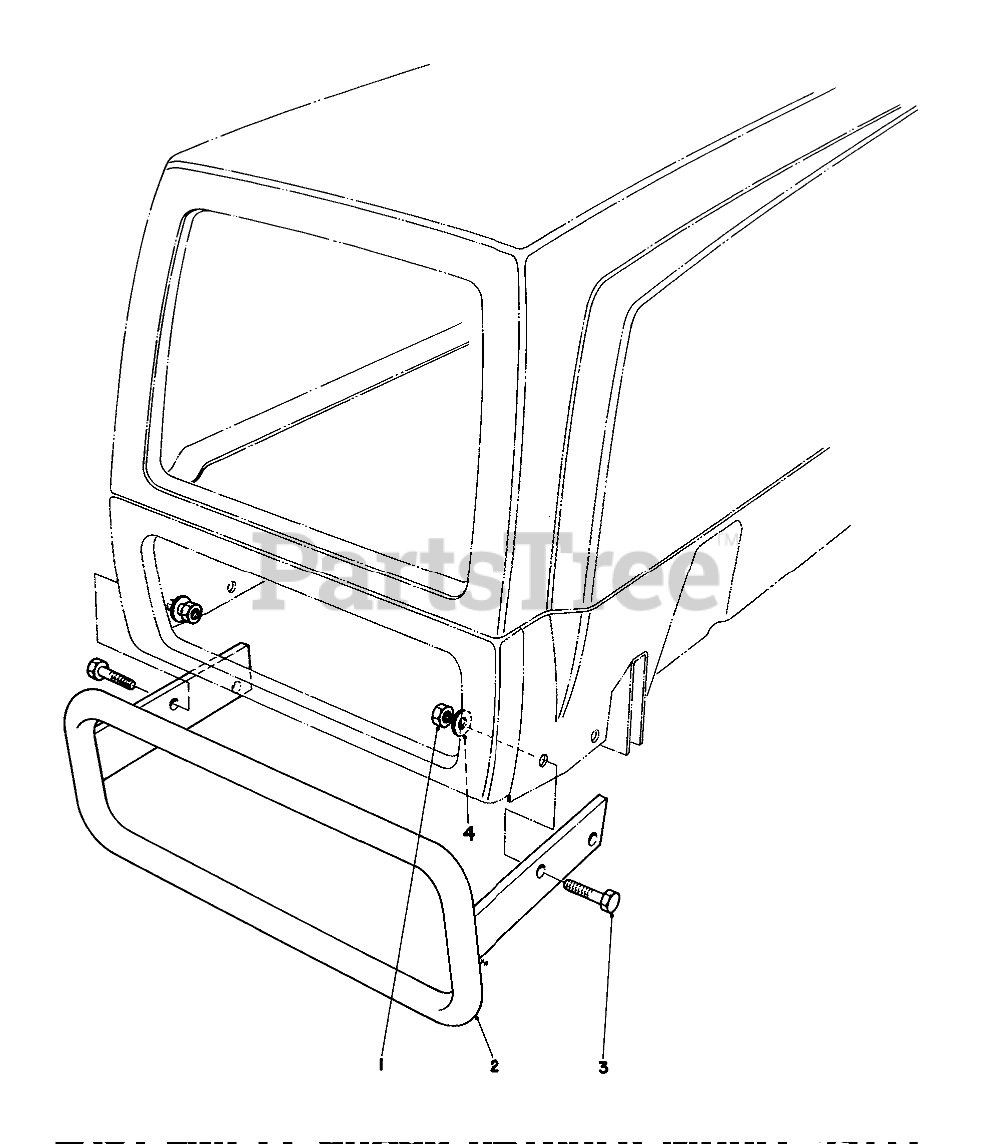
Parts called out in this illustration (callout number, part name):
1	NUT-LOCK, CONE
2	Bumper
3	SCREW-HH
4	WASHER-PLAIN
